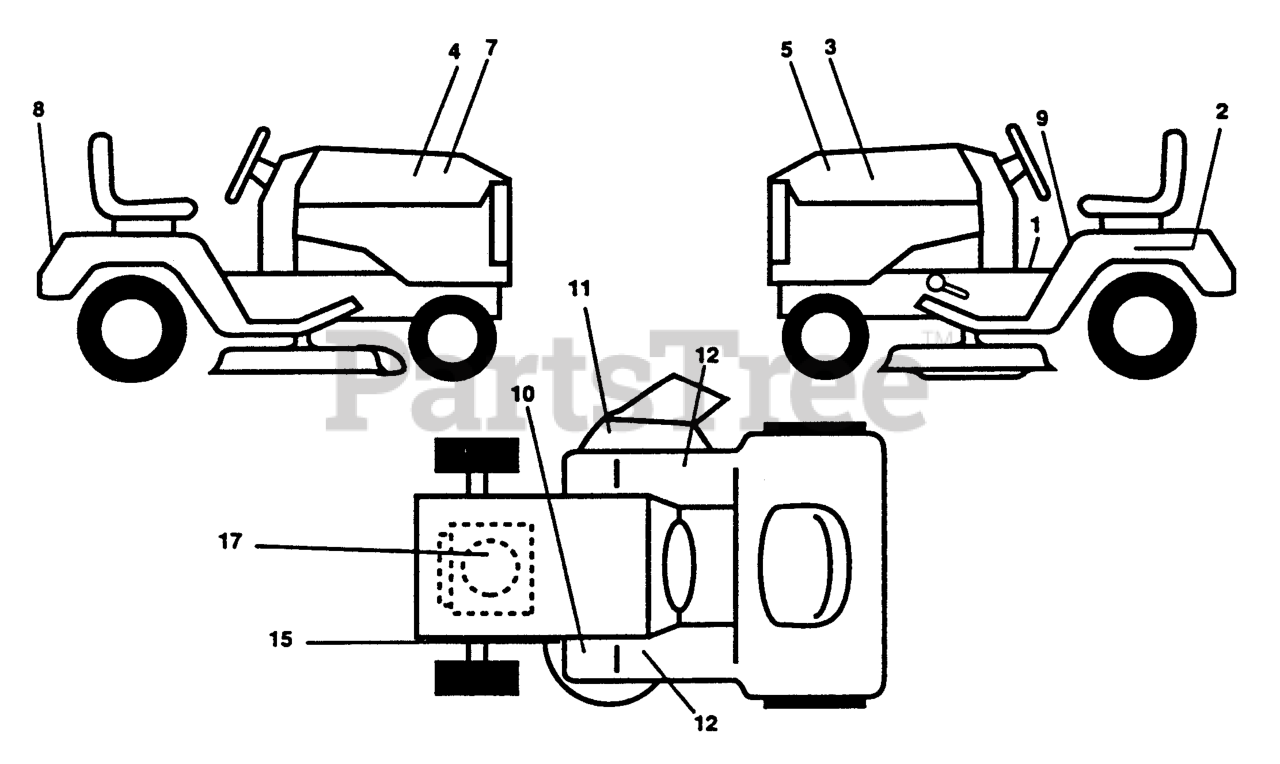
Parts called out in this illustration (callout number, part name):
1	DECAL DASH
3	DECAL HOOD RH
4	DECAL HOOD LH
5	Decal Ins Hd LH
7	Decal Ins Hd RH
8	DECAL FENDER NLA
9	DECAL CAUTION
11	DECAL WARNING (ENGLISH/FRENCH)
12	FOOTREST PAD
15	DECAL V-BELT SCHEMATIC
17	DECAL ENGINE
